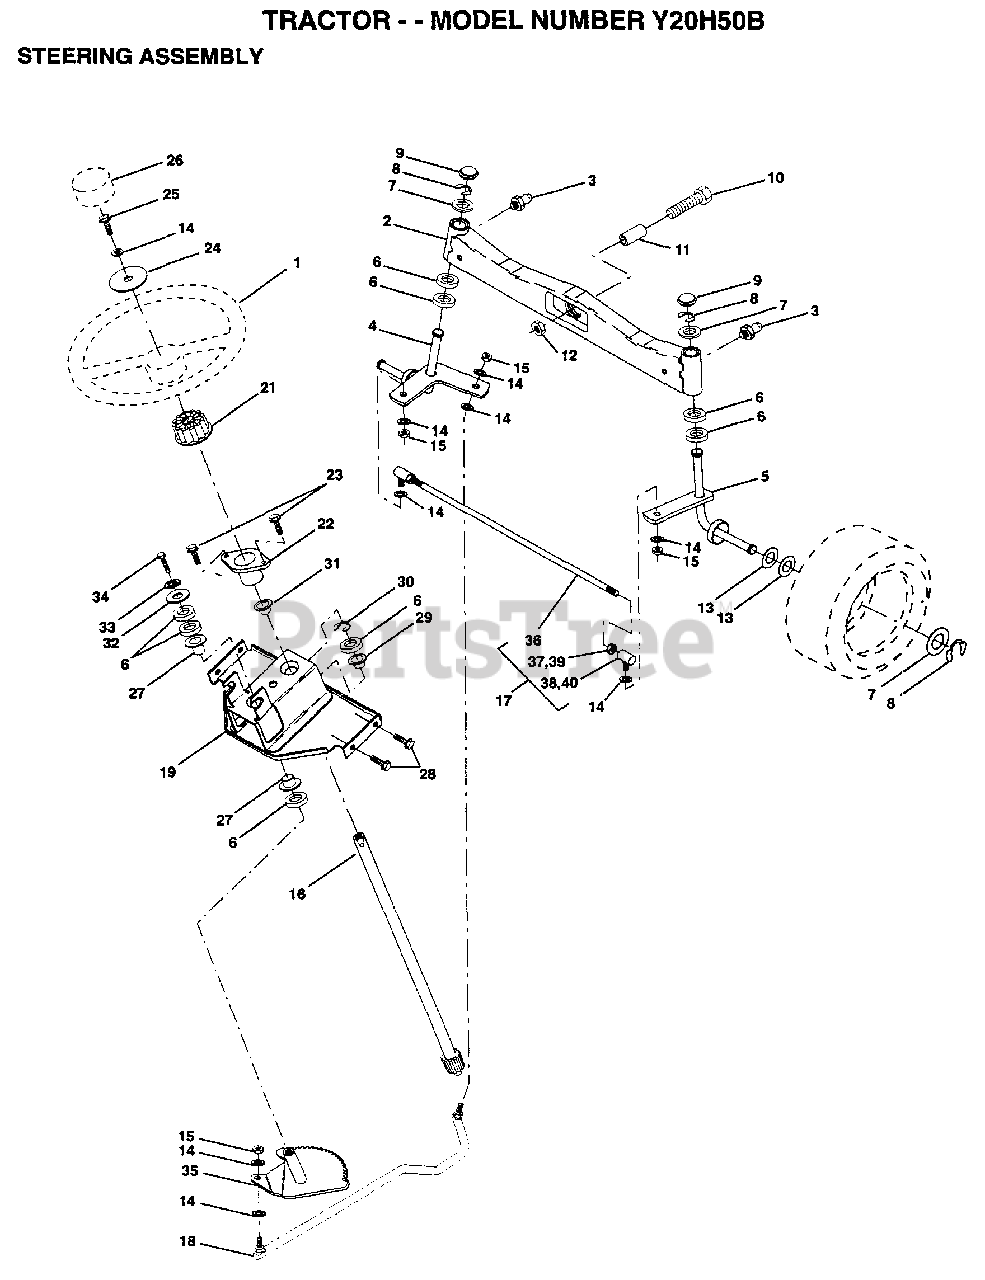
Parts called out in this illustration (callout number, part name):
1	Wheel Steering
3	ZERK M
4	SPINDLE.ASM.LH
6	WASHER .T
7	WASHER
8	RING
9	CAP
10	BOLT
11	SPACER BEARING
12	"NUT-LOC,FLANGE LT"
13	WASHER (2513009)
14	LOCKWASHER
16	SHAFT.STEER.VGT
17	ROD.ASM.TIE.BALL
18	DRAGLINK.BALL.JOI
21	ADAPTER LT
24	WASHER T
25	BOLT
26	INSERT STEERING
27	COL. SRTG. BEAR.
28	SCREW
29	FLANGE GT, BEAR.
30	KLIP RING
31	BUSHING.NYLINER.
32	WASHER
33	LOCKWASHER
34	BOLT
35	GEAR.ASM.SECTOR.
37	NUT
38	JOINT.RH
39	NUT
40	JOINT.LH
